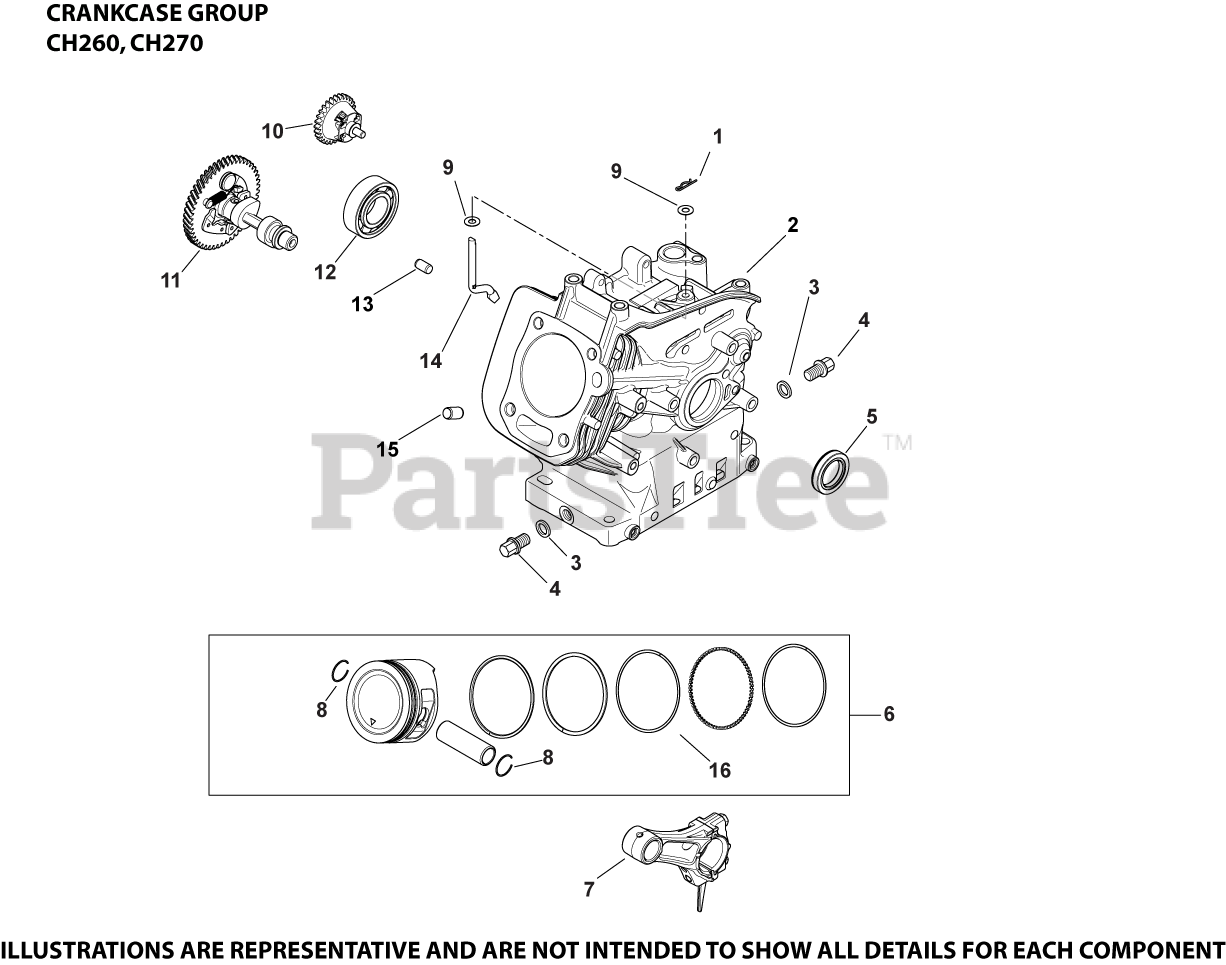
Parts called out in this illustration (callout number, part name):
1	CLIP, GOVERNOR SHAFT
2	CRANKCASE ASSEMBLY
3	WASHER, DRAIN PLUG - (#1846801S)
4	KIT, DRAIN PLUG
5	SEAL, OIL
6	KIT, PISTON USE 17 874 10-S
6	KIT, PISTON (0.25 O.S.)
7	ROD, CONNECTING ASSEMBLY
8	RETAINER, PISTON PIN
9	WASHER, FLAT (13MM OD)
10	GOVERNOR ASSEMBLY
11	CAMSHAFT ASSEMBLY
12	BEARING, BALL
13	PIN, DOWEL
14	SHAFT, GOVERNOR CROSS
15	DOWEL, CYLINDER HEAD-(#1438013S)
16	RING SET, PISTON
16	RING SET
16	RING SET (0.25 O.S.)
